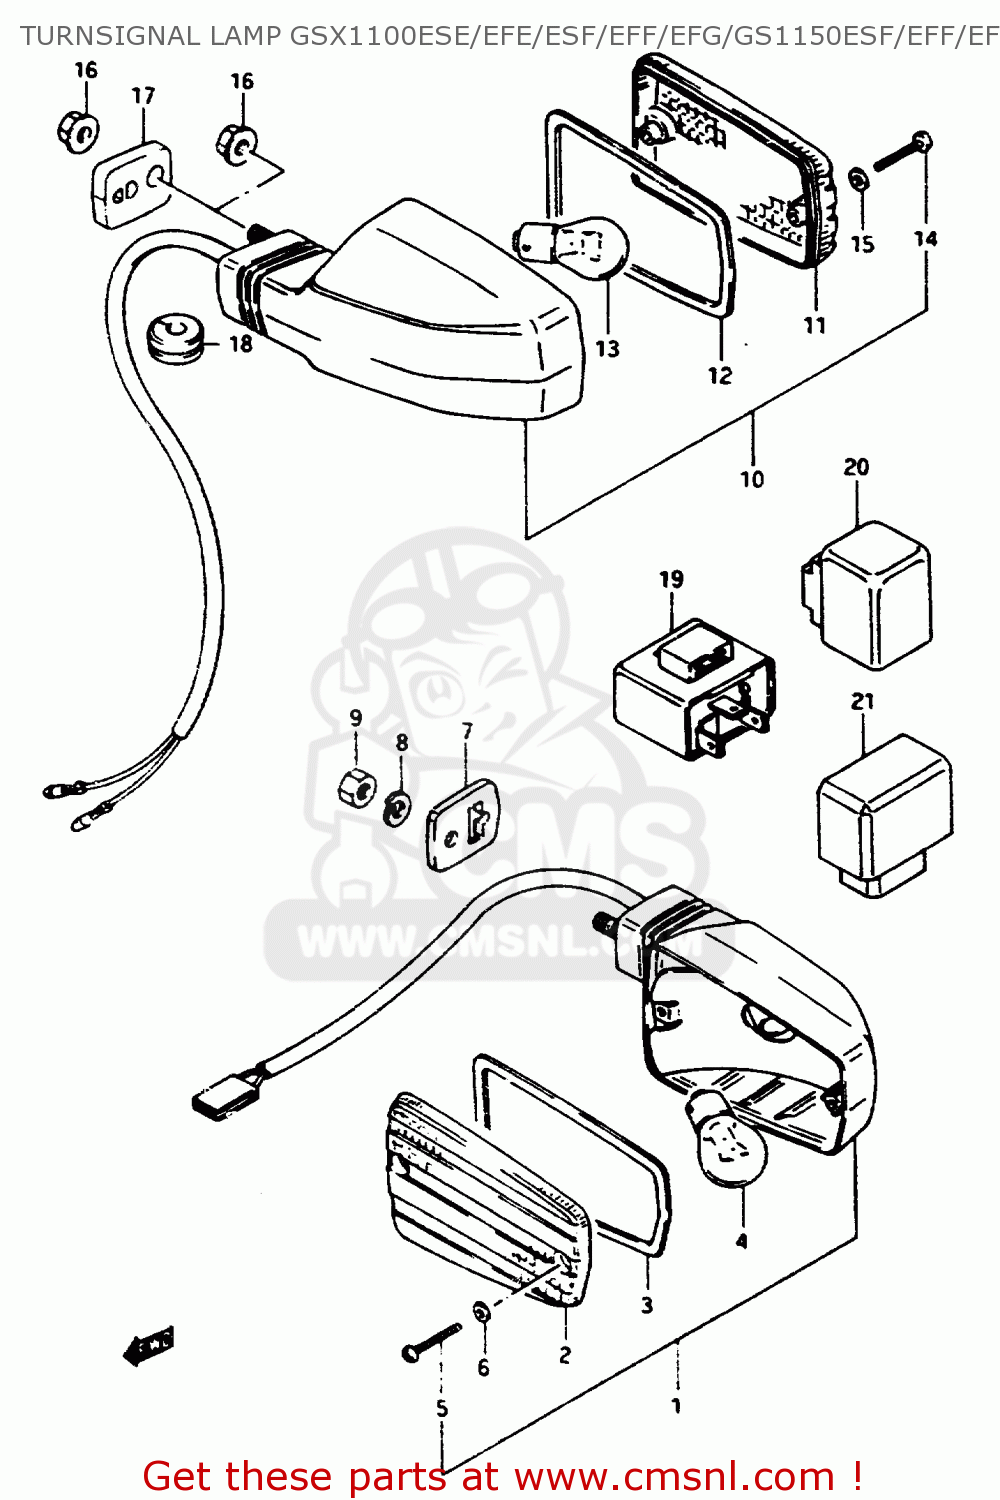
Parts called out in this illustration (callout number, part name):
1	LAMP ASSY, FRONT TURN SIGNAL
2	LENS
3	GASKET (NAS)
4	BULB(12V21W)
5	SCREW
6	GASKET (NAS)
7	SPACER,FRONT TURN SIGNAL
8	LOCK WASHER
9	NUT
10	LAMP ASSY, REAR TURN SIGNAL
11	LENS
12	GASKET (NAS)
13	BULB(12V21W)
14	SCREW
15	GASKET (NAS)
16	NUT
17	SPACER
18	GROMMET
19	RELAY ASSY,TURNSIGNAL
20	RELAY ASSY,TUR
21	UNIT,TURN SIGNAL CONTROL
